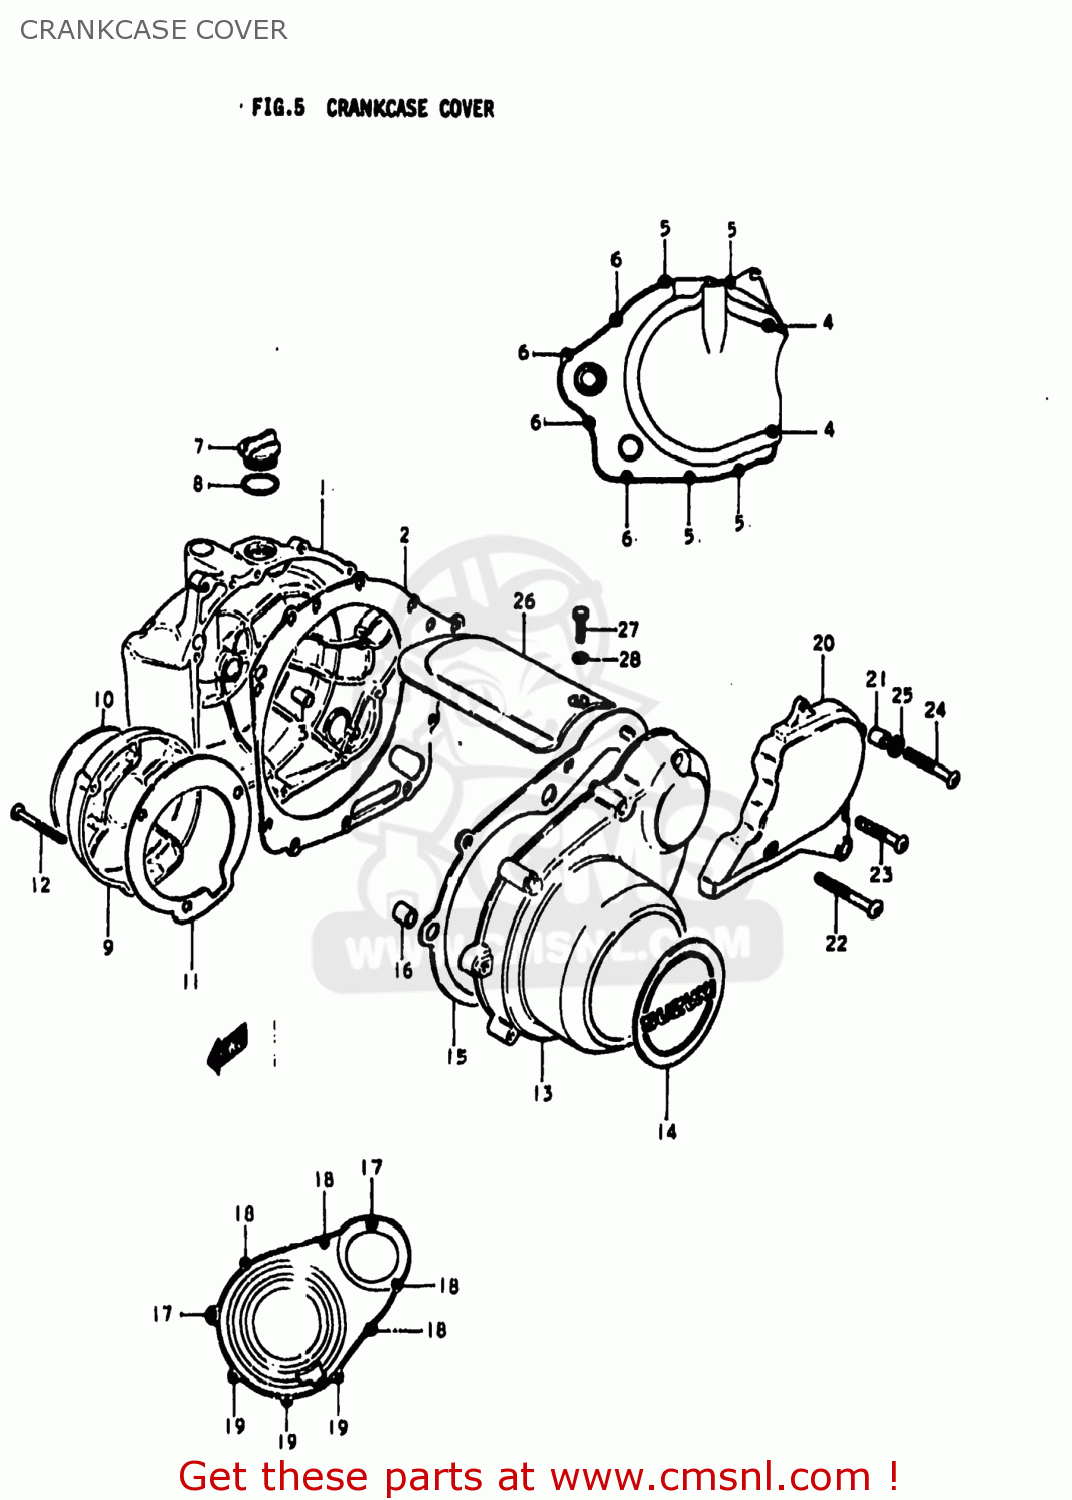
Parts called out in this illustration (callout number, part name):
1	COVER,CLUTCH
2	GASKET,CLUTCH COVER (MCA)
3	PIN
4	SCREW 6X65
5	SCREW
6	SCREW
7	CAP
8	O RING(D:2.2,ID:32)
9	COVER,CONTACT BREAKER
10	EMBLEM
11	GASKET,CONTACT BREAKER COVER (NAS)
12	SCREW
13	COVER
14	EMBLEM
15	GASKET,MAGNETO COVER (MCA)
16	PIN
17	SCREW (6X45)
18	SCREW
19	SCREW (6X35)
20	COVER,SPROCKET
21	PIN
22	SCREW
23	SCREW
24	SCREW
25	WASHER 6MM
26	COVER,STARTER MOTOR
27	BOLT
28	WASHER
